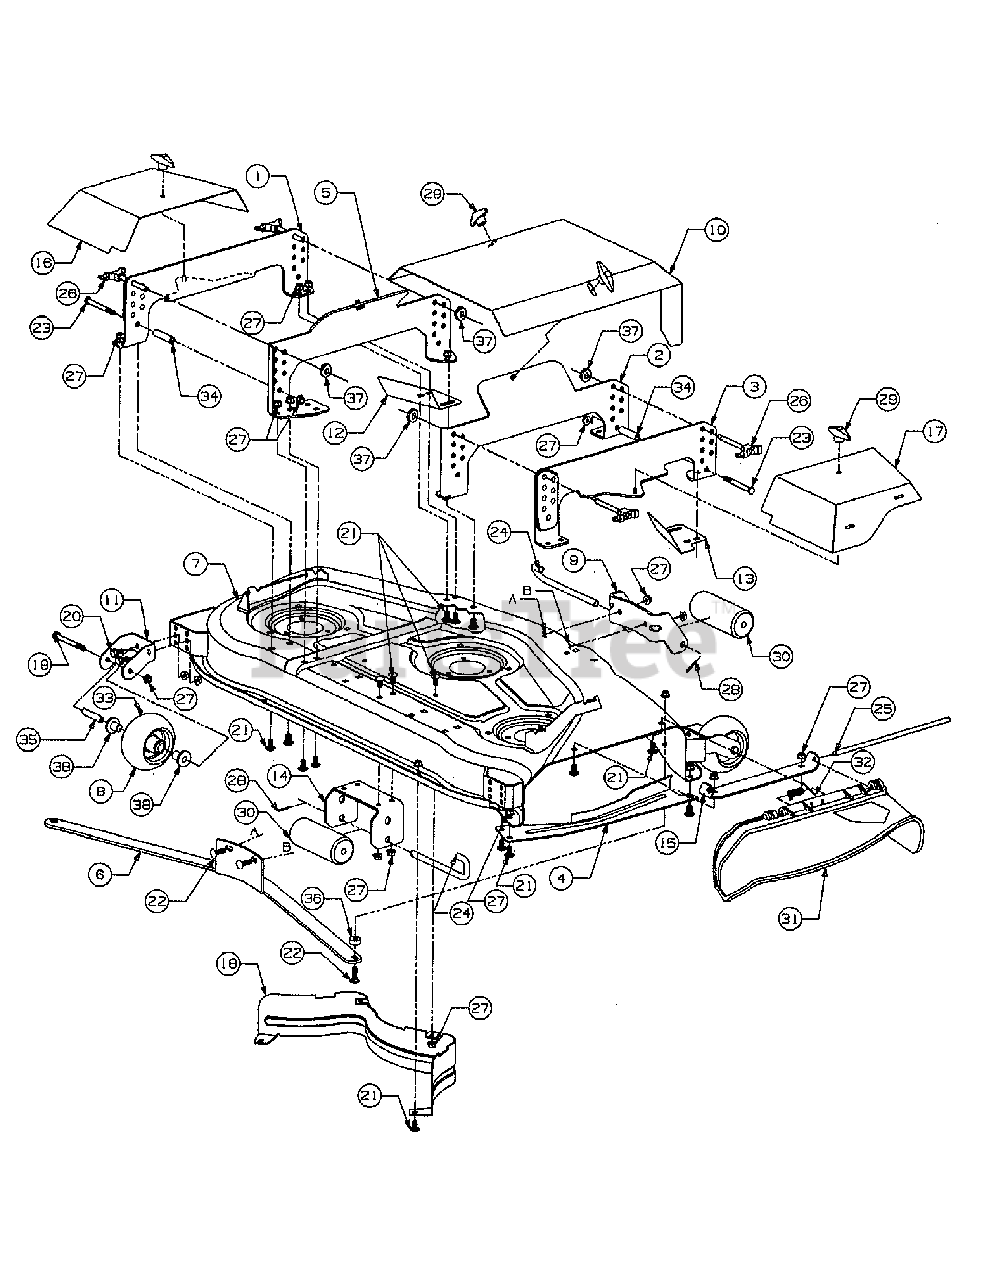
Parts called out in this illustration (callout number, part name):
5	Hanger, LH Inner
7	Graphic, Danger Cut Finger
7	Graphic, Danger
8	Wheel Assembly, 5'' Deck w/ Fitting
8	Wheel Assembly, Deck
10	Graphic, Belt Cover Front
10	Graphic, 4815F, Belt Cover Right
13	Plate, RH Filler
19	Screw, Hex Cap, 3/8-16 x 4.75 x Gr 5
20	Screw, Hex Wash Sf Tapp, 3/8-16 x 4.25
21	Bolt, Sht Nk Carriage
22	3/8-106 x .88 Gr 5
23	Screw, Hex Cap
24	Pin, Roller, 1/2 Dia x 7.31
25	Pin, Hinge, .375 Dia x 12.55
26	Pin, Quick Release 3/8 Dia
27	Nut, Hec Flanged Lock, 3/8-16
28	Pin, Cotter, 1/8 Dia x 1.0
29	Knob, Wing Nut
31	Deflector Chute
31	Graphic, Danger Cut Finger
32	Spring, Torsion
33	Fitting, Lube
34	Spacer, Deck Hanger
35	Spacer, Deck Wheel
36	Spacer, Front Bar
37	Washer, Flat .385 x .870 x .092 Thk
38	Bearing Flange
